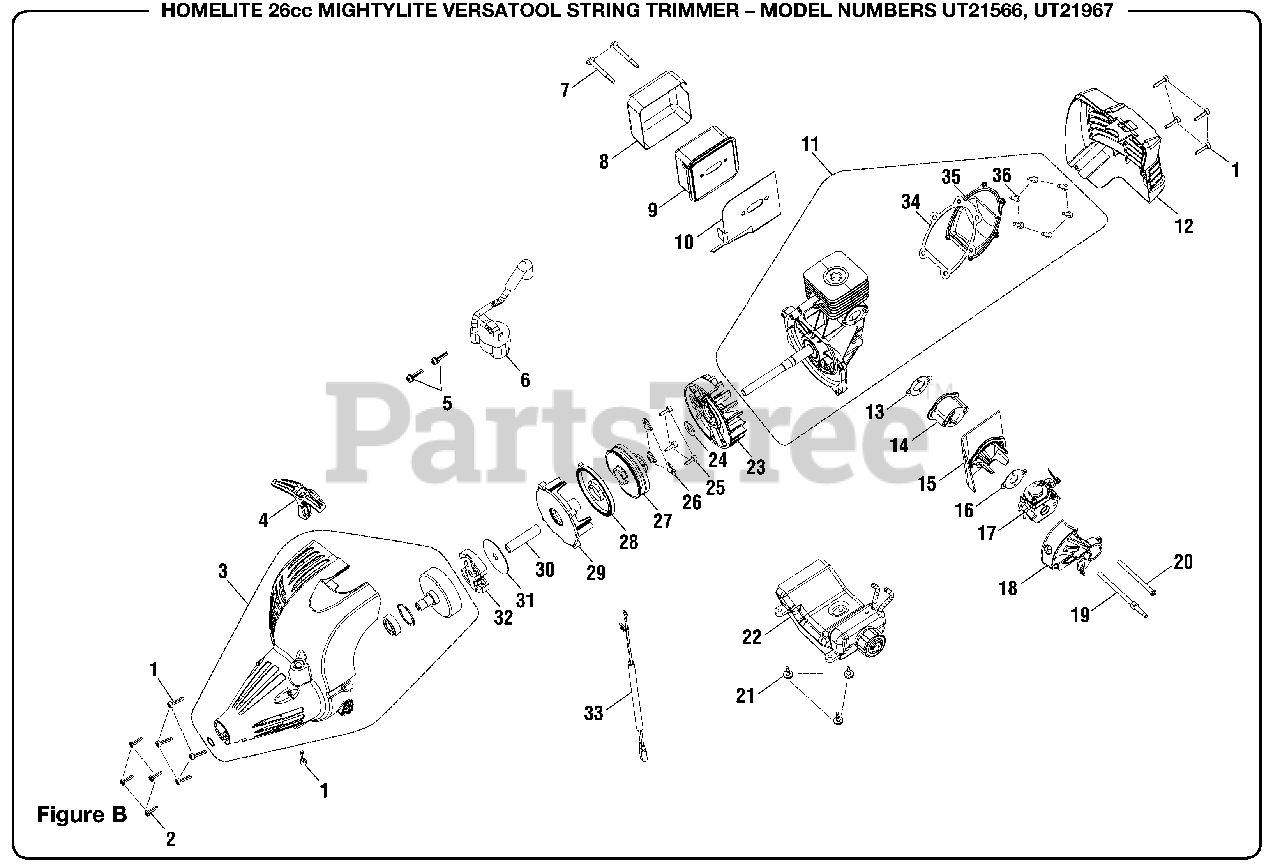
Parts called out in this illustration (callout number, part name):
1	Screw (M4 x 18 mm)
2	Screw (M4 x 16 mm)
3	Front Housing Assembly
4	Pulley Handle
5	Screw (M4 x 19 mm)
6	Ignition Module
7	Screw (10-24 x 2-3/16 in.)
8	Heat Shield
9	Muffler Assembly
10	Muffler Gasket
11	Short Block Assembly
12	Rear Housing
13	Intake Gasket
15	Heat Dam Deflector
16	Carburetor Gasket
17	Carburetor
18	Choke Base
19	Double Sided Hex Bolt
20	Bolt (M5 x 70 mm)
21	Screw (M4 x 10 mm Shoulder)
22	Fuel Tank Assembly w/Cap (UT21566)
23	Flywheel Assembly
24	Washer
25	Screw (M4 x 14 mm)
26	Pulley Retainer
27	Starter Pulley Assembly
28	Spring & Container Assembly
29	Starter Housing
30	Spacer Tube
31	Clutch Washer
32	Clutch Assembly
33	Lead Assembly
34	Gasket
35	Crankcase Cover
36	Screw (M4 x 12 mm)
